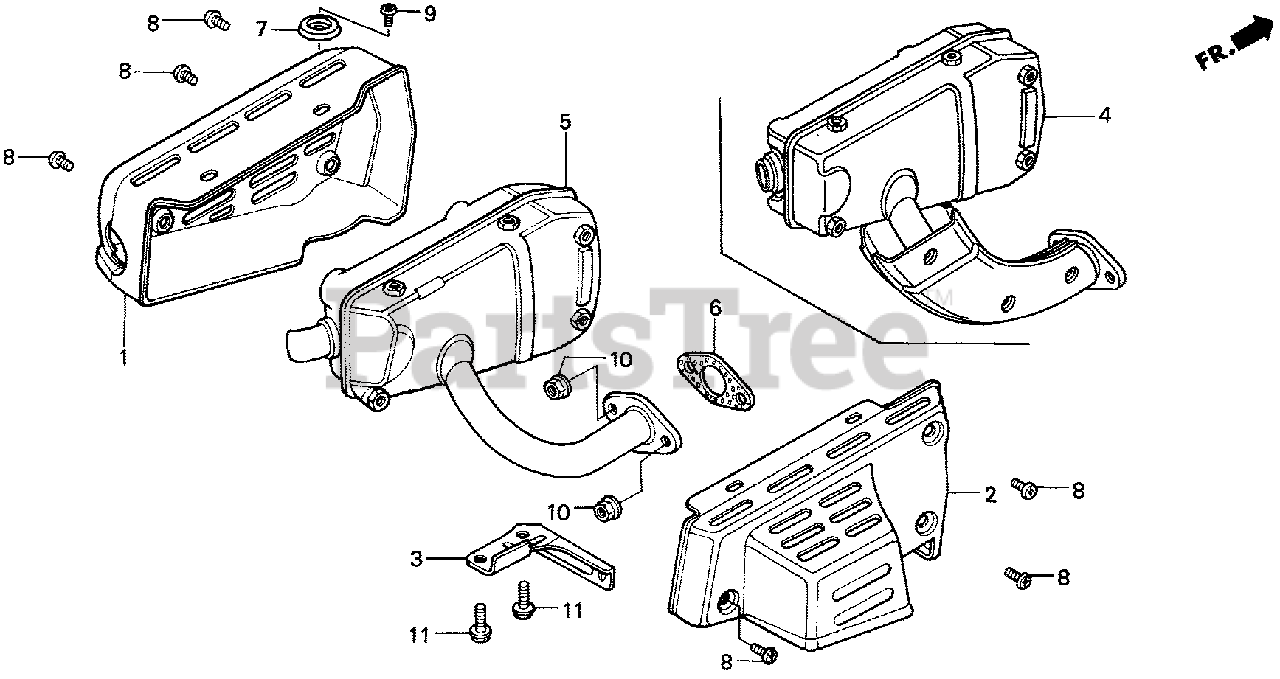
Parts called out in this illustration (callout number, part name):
1	PROTECTOR, MUFFLER
2	SEPARATOR, MUFFLER
3	STAY, MUFFLER
5	MUFFLER (NOT AVAILABLE)
6	GASKET, MUFFLER
8	SCREW, PAN (6X6)
9	SCREW, PAN (6X6)
10	NUT, FLANGE (8MM)
11	BOLT, FLANGE (6X16)
